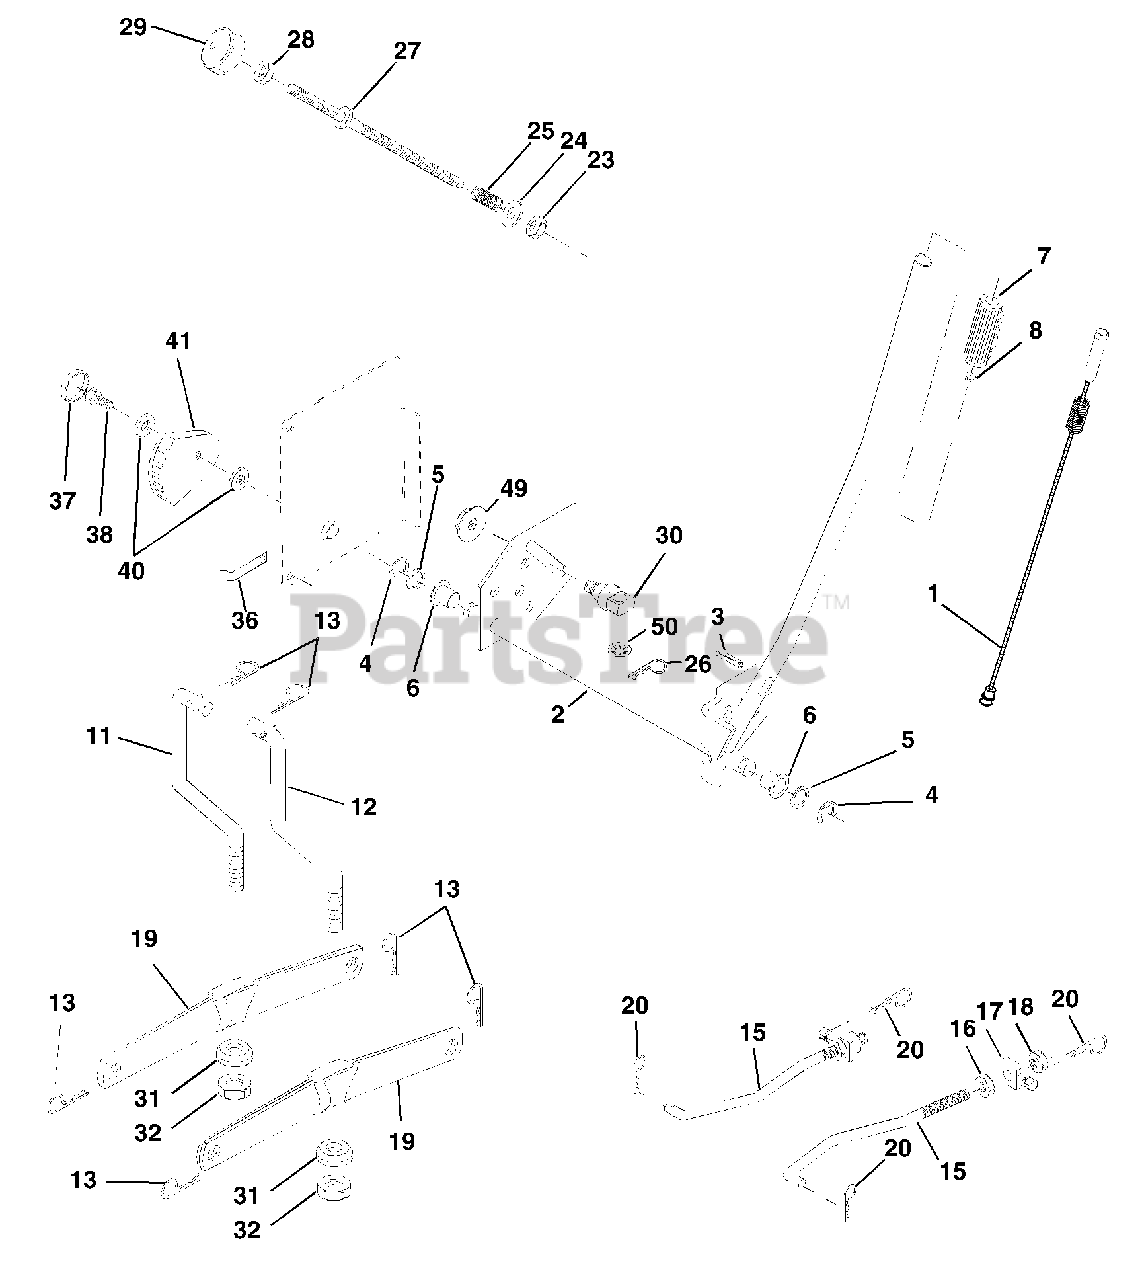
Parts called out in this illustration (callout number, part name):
1	Wire Asm Inner/Sprg W/plunger LT
2	Shaft Asm Lift RH w/Inf
3	Pin Groove 1 500 Zinc
4	E Ring #5133-62
5	Washer 21/32 X 1 X 21 Ga
6	Bearing Nylon Blk 629 Id
7	Grip Handle
8	Button Plunger Yellow
11	Link Lift LH Fixed Length
12	Link Lift RH Fixed Length
13	Retainer Spring
15	Link Front
16	Nut Jam Hex 1/2-13 Unc
17	Trunnion Blk Zinc
18	Nut Lock W/Wsh 1/2-13 Unc
19	Arm Suspension Rear
20	Retainer Spring
23	Nut Special
24	Washer 13/32 X 5/8 X 16 Ga
25	Spring 2-1/8"
26	Retainer Clip
27	Rod Adj Lift Zinc 7.49 Wrk Lg
28	Nut Hex Jam 3/8-16 Unc
29	Knob Inf 3/8-16 Unc Blk W/sym
30	Trunnion Infin Height
31	Bearing Pvt Lift
32	Nut Crownlock 3/8 - 24
36	Pointer Height Indicator
37	Plug Hole Blk 1.485/1.515 Dia.
38	Screw 5/16-18 x 1
40	Washer 11/32 x 1-1/2 10 Ga.
41	Indicator Height STLT
49	Nut Hex Flange Lock
50	Nut PUsh Phos & Oi
